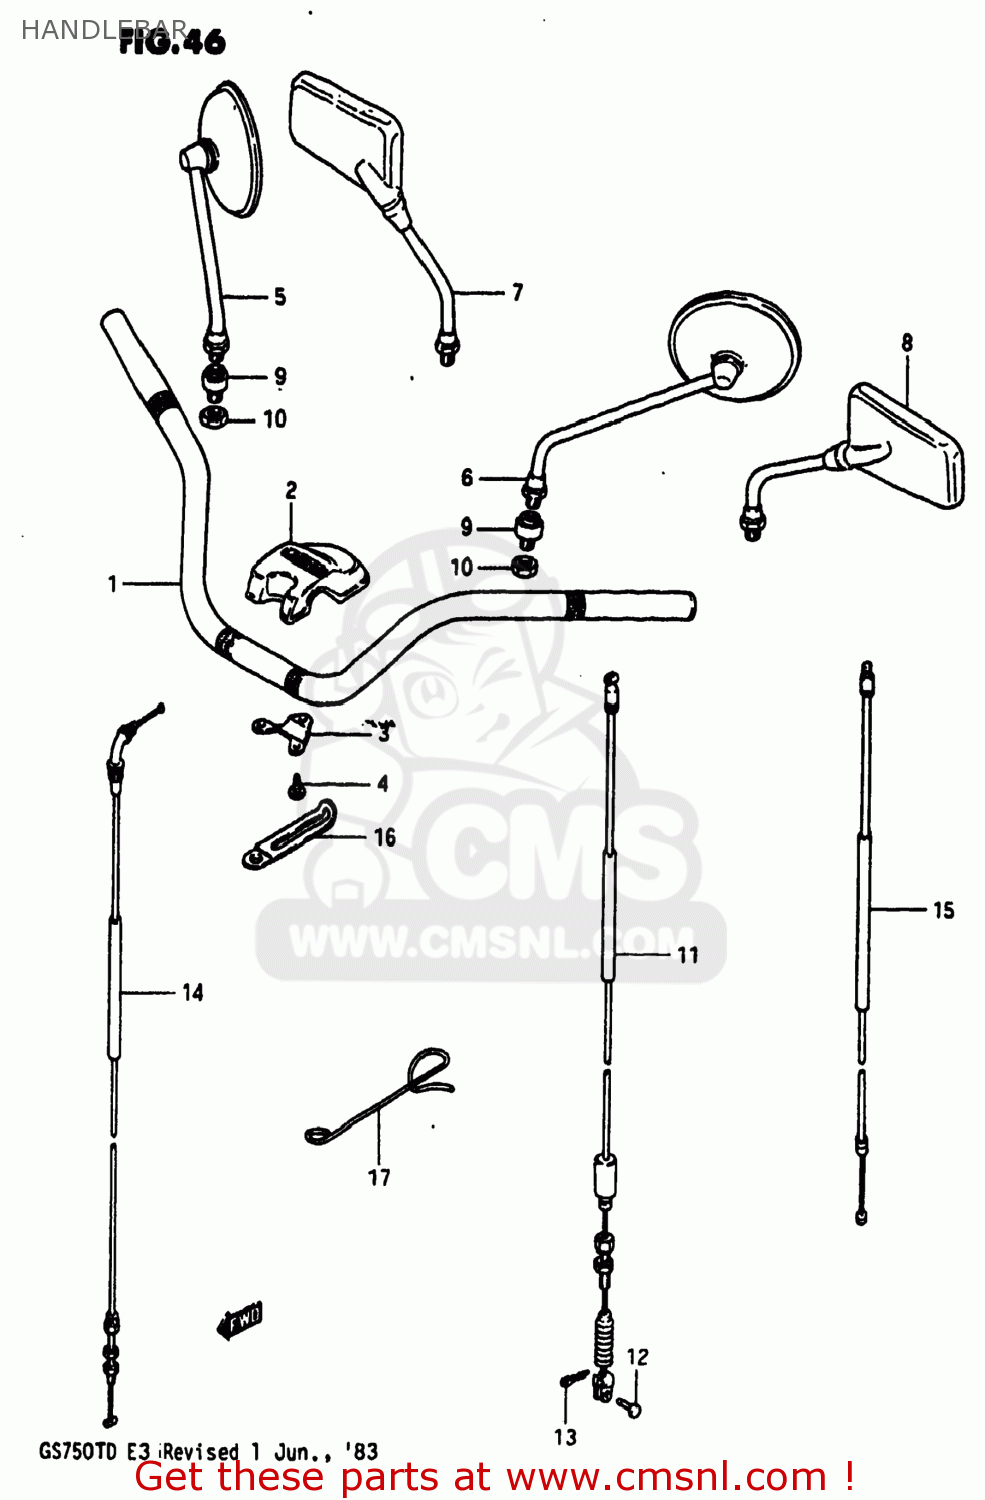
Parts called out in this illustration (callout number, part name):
1	HANDLEBAR
2	COVER,STEERING HEAD
3	BRACKET,HEAD COVER
4	SCREW
5	MIRROR ASSEMBLY,RIGHT
6	MIRROR ASSEMBLY,LEFT
7	MIRROR ASSEMBLY,REAR VIEW
8	MIRROR ASSEMBLY,REAR VIEW
9	CUSHION,REAR VIEW MIRROR
10	NUT
11	CABLE ASSY,CLUTCH
12	PIN(L:15)
13	PIN
14	CABLE ASSEMBLY,THROTTLE
15	CABLE,STARTER
16	CLAMP
17	GUIDE,CLUTCH CABLE
